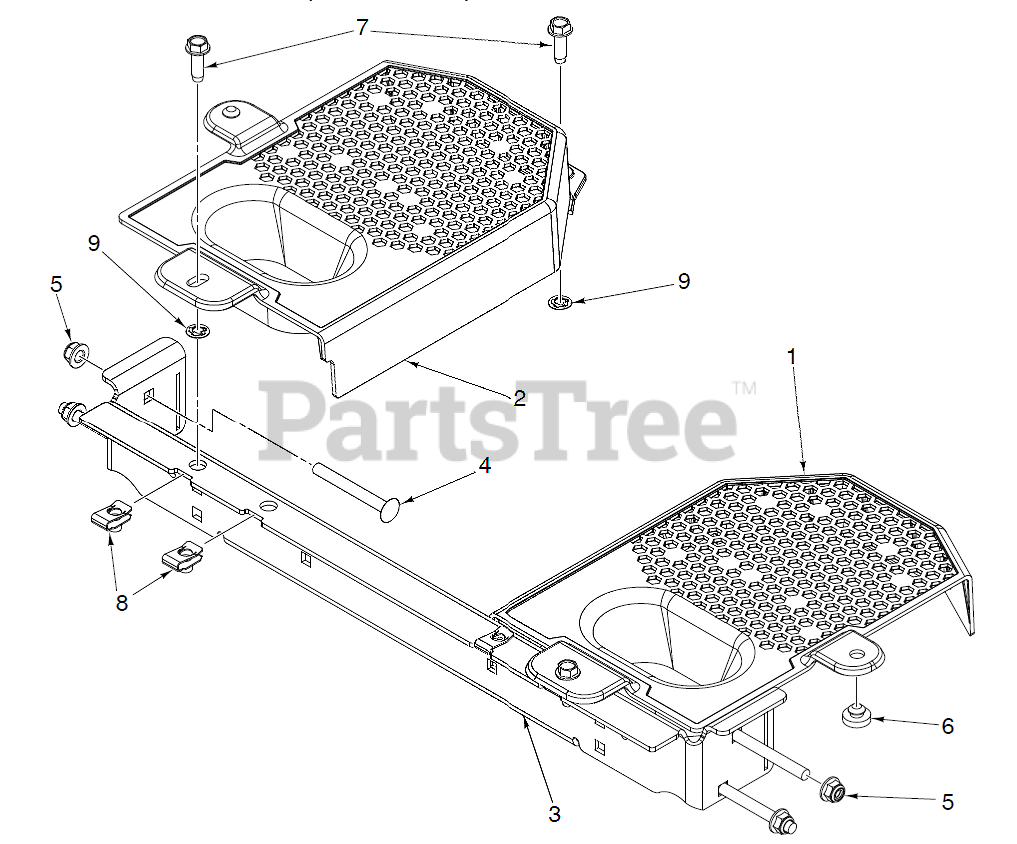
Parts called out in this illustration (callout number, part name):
1	Shields
2	Shields
3	Brackets
4	BOLT HEX FLGHD 5/16-18X3 GR. 5
5	NUT HEXAGON FLANGE 5/16-18 ST
6	GROMMET, BUMPER
7	SCREW HEX HEAD W/ WASHER 5/16-
8	U-CLIP 5/16-18 NUT RETAINER
9	WASHER 5/16"
